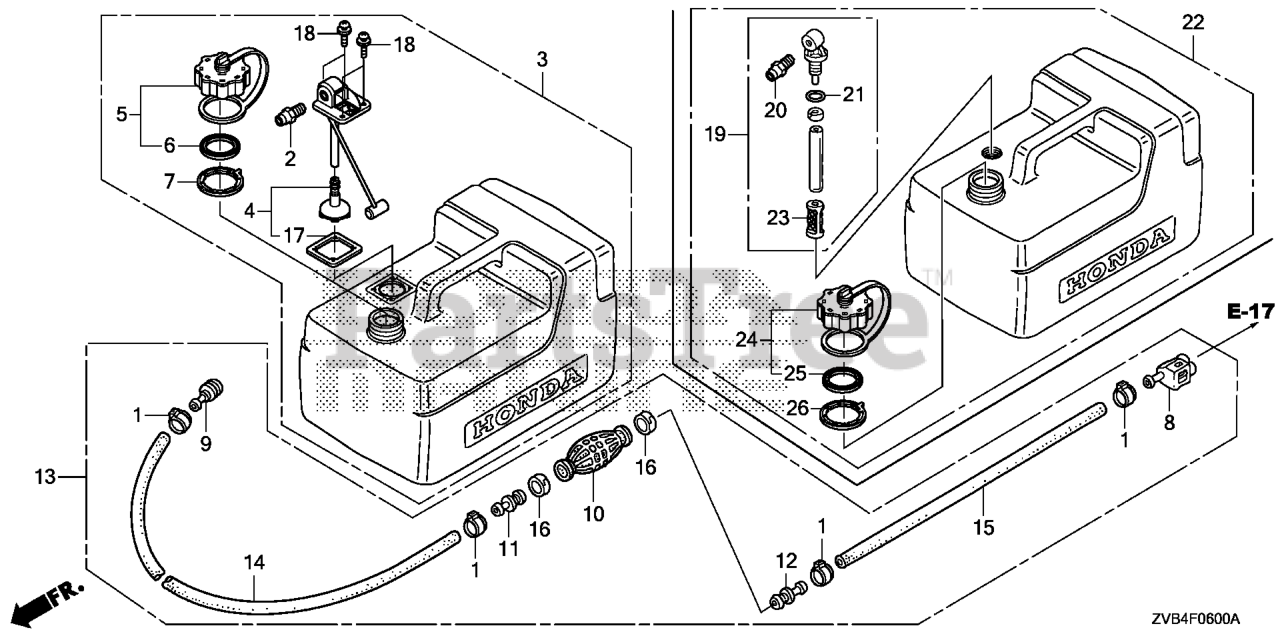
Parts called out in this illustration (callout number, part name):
1	CLAMP, FUEL TUBE (14.0) (CONNECTOR TYPE)
2	FITTING, QUICK DISCONNECT Use from Frame SN 1205705.
3	TANK ASSY., FUEL
4	FILTER KIT, FUEL
5	CAP, FUEL FILLER
6	GASKET, FUEL CAP
7	RETAINER, PRESSURE RELIEF
8	CONNECTOR ASSY., FUEL (A)
9	CONNECTOR, FUEL (CONNECTOR TYPE)
10	BULB, PRIMER
11	VALVE, IN.
12	VALVE, OUTLET
13	TUBE ASSY., FUEL TANK
14	TUBE, FUEL LONG (7.3X2000)
15	TUBE, FUEL SHORT
16	BAND, TUBE CLIP (20MM)
17	GASKET, FUEL PICK-UP
18	BOLT-WASHER (5MM) (SEAL)
19	JOINT ASSY., FUEL
20	FITTING, QUICK DISCONNECT Use from Frame SN 1205705.
21	O-RING Use from Frame SN 1300962.
22	TANK, FUEL (12L)
23	FILTER, FUEL
24	CAP, FUEL FILLER
25	GASKET, FUEL CAP
26	RETAINER, PRESSURE RELIEF
